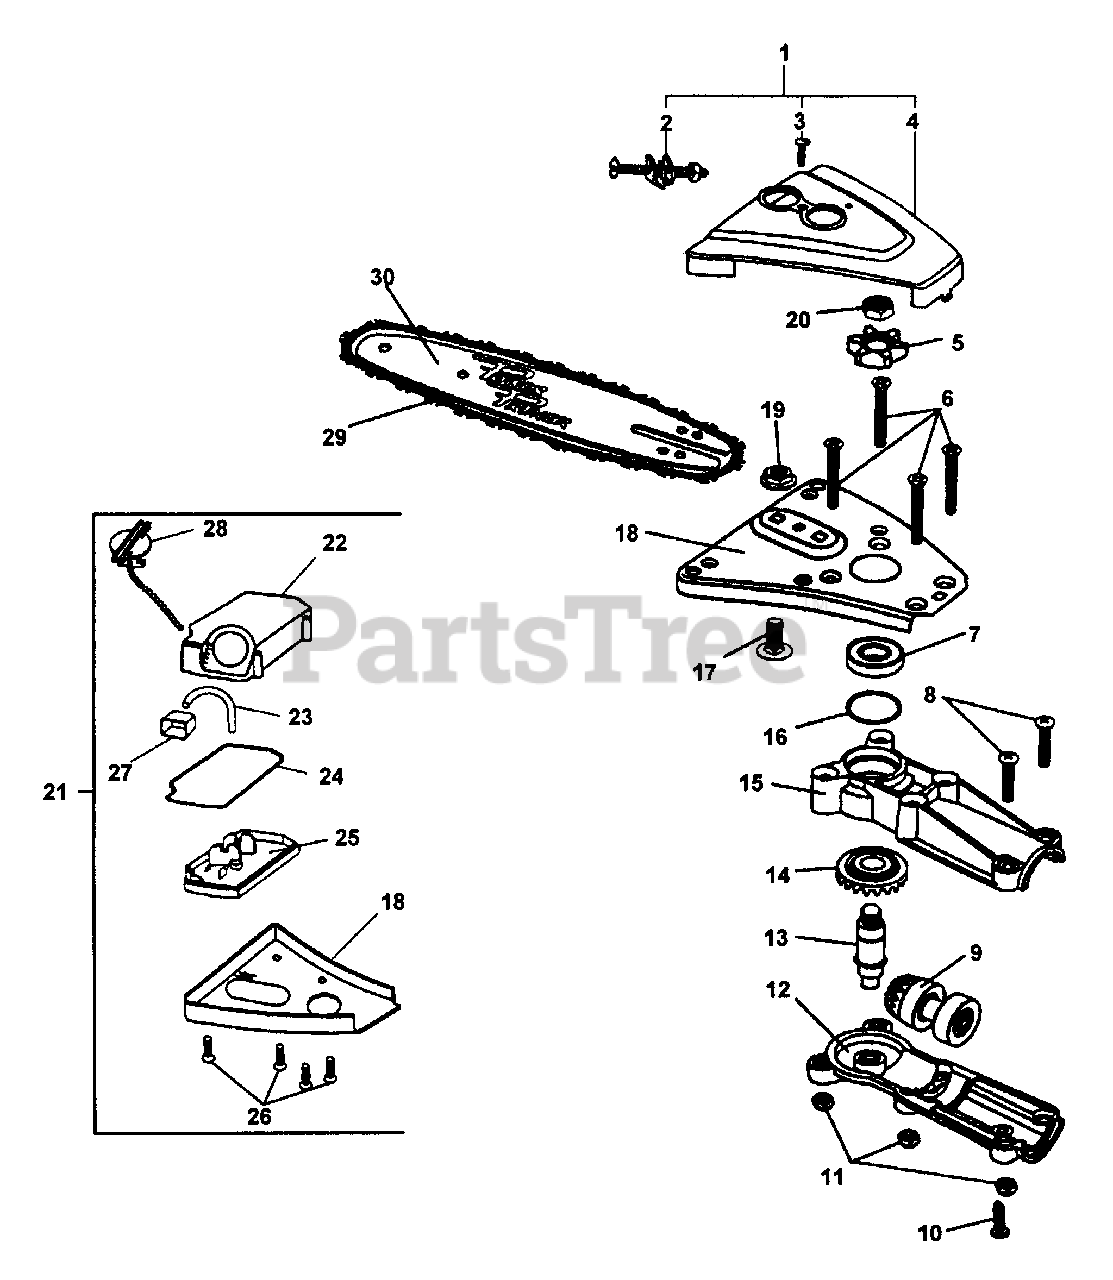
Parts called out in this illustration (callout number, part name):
1	SPROCKET COVER ASSY
2	TENSIONER KIT
3	SCREW - 8-32 X 1"
4	GUARD, SPROCKET
5	SPROCKET
7	BEARING, BALL - 6001 DDU
8	SCREW - 10-24 X 1-1/4"
9	SHAFT GEAR ASSY
10	SCREW
11	LOCKNUT - 10-24
12	CASE, GEAR - RIGHT
13	SHAFT GEAR ASSY
14	GEAR - BEVEL
15	CASE, GEAR - RIGHT
16	SHIM .004"
17	BOLT
18	SAW BAR CARRIER
19	NUT - FLANGE
21	SEMI-AUTO OILER ASSY
22	TANK, OIL (CAP SIDE)
23	PIPE - 3X5X70 -- BLACK
25	TANK, OIL (CHAIN SIDE)
26	SCREW
27	CUP, OIL
28	CAP ASSY
29	SAW CHAIN - 10" (25cm)
30	GUIDE BAR - 10" (25cm)
